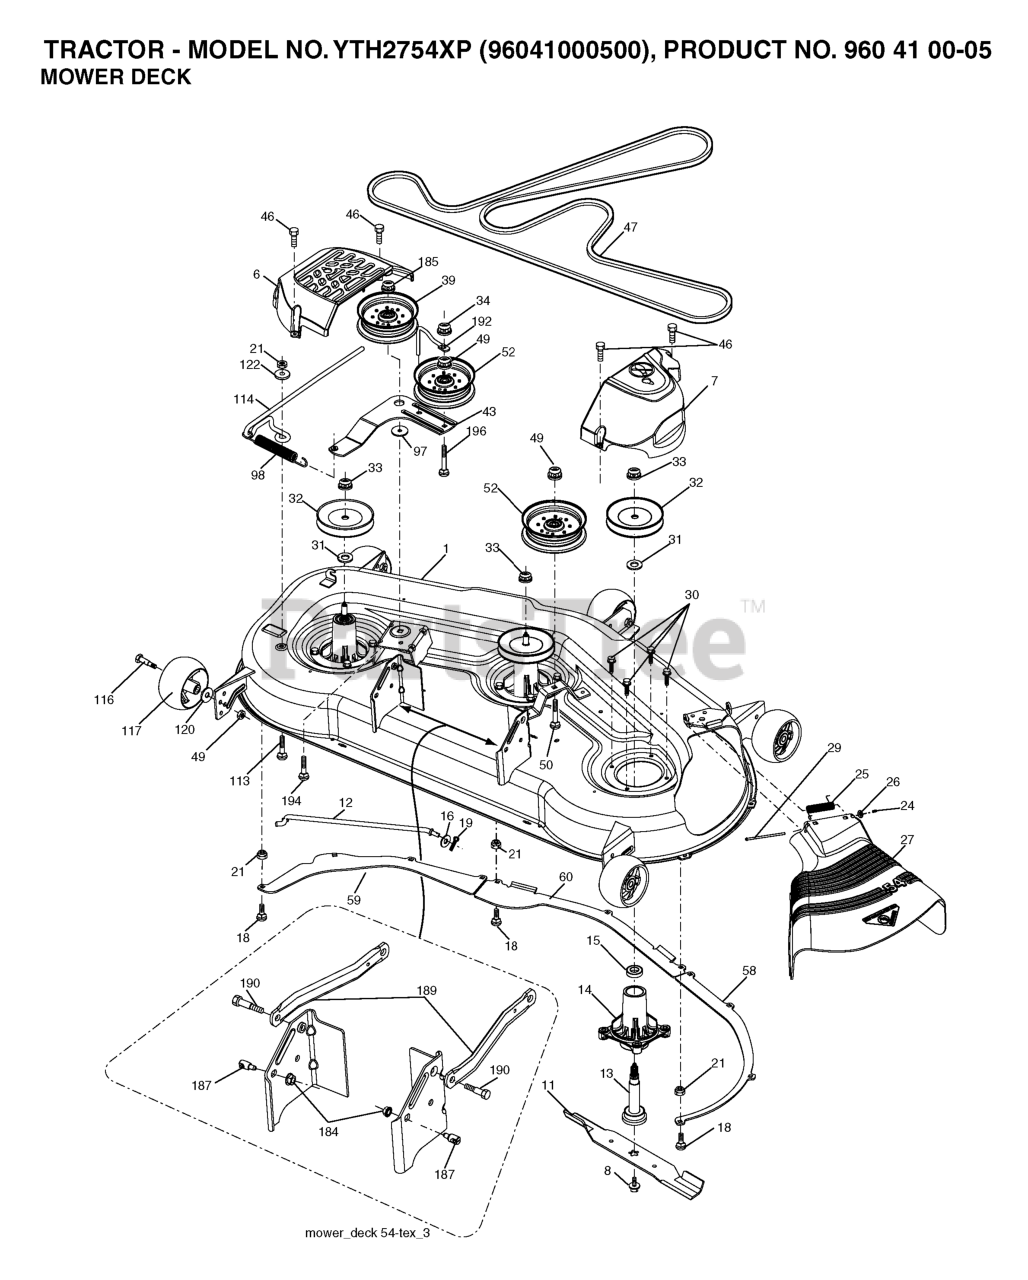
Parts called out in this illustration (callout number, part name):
1	DECK.WELDMENT.54'
6	COVER.MANDREL.LH.54"20
7	COVER.MANDREL.RH.54.20
8	BOLT 7/16 ASM BLADE
11	BLADE.BAGGING.54"
12	ROD.ANTI.SWAY.48/54"TE
13	SHAFT ASM MANDREL
14	RP.HOUSING.MANDREL.4PT.
16	WASHER
18	BOLT
19	PIN.COTTER.5/16.BOW TI
21	LOCKNUT
24	CAP-SLEEVE LT
25	SPRING, TORSION
26	NUT PUSH M
27	DEFLECTOR
29	ROD.HINGE
30	SCREW, WASHER HEAD
31	WASHER.SPACER.MANDREL
32	PULLEY MANDREL
33	NUT.FLANGE.LOCK.TOP
39	PULLEY.IDLER.MWR.STATI.LH
46	SCREW.1/4-20X5/8
47	RP.BELT.DRIVE.54."2006
49	NUT LOCK FLG 3/8-16 UNC
52	PULLEY.IDLER.2006
58	BAFFLE.RIGHT.54"
59	BAFFLE.LEFT.54"
60	BAFFLE CENTER 54" MOWER
98	SPRING, DECK DRIVE
114	HARNESS.IGN.PLM.CBL.CL.AM/HM
116	BOLT.SHOULDER.3/8-16X3-5/8.
117	RP WHEEL. GUAGE RALLY
120	WASHER
122	BUSHING.RELIEF.TENSION
184	NUT LOCK HEX FLANGE 5/16-18
185	NUT.LOCK.FLANGE.7/16
187	STUD.FASTNER.W/ANTI-ROTATE
189	ARM.SUSPENSION.MOWER
190	BOLT.SHOULDER
192	KEEPER.BELT.IDLER.54"T
194	BOLT.CARR.SQNK.7/16
